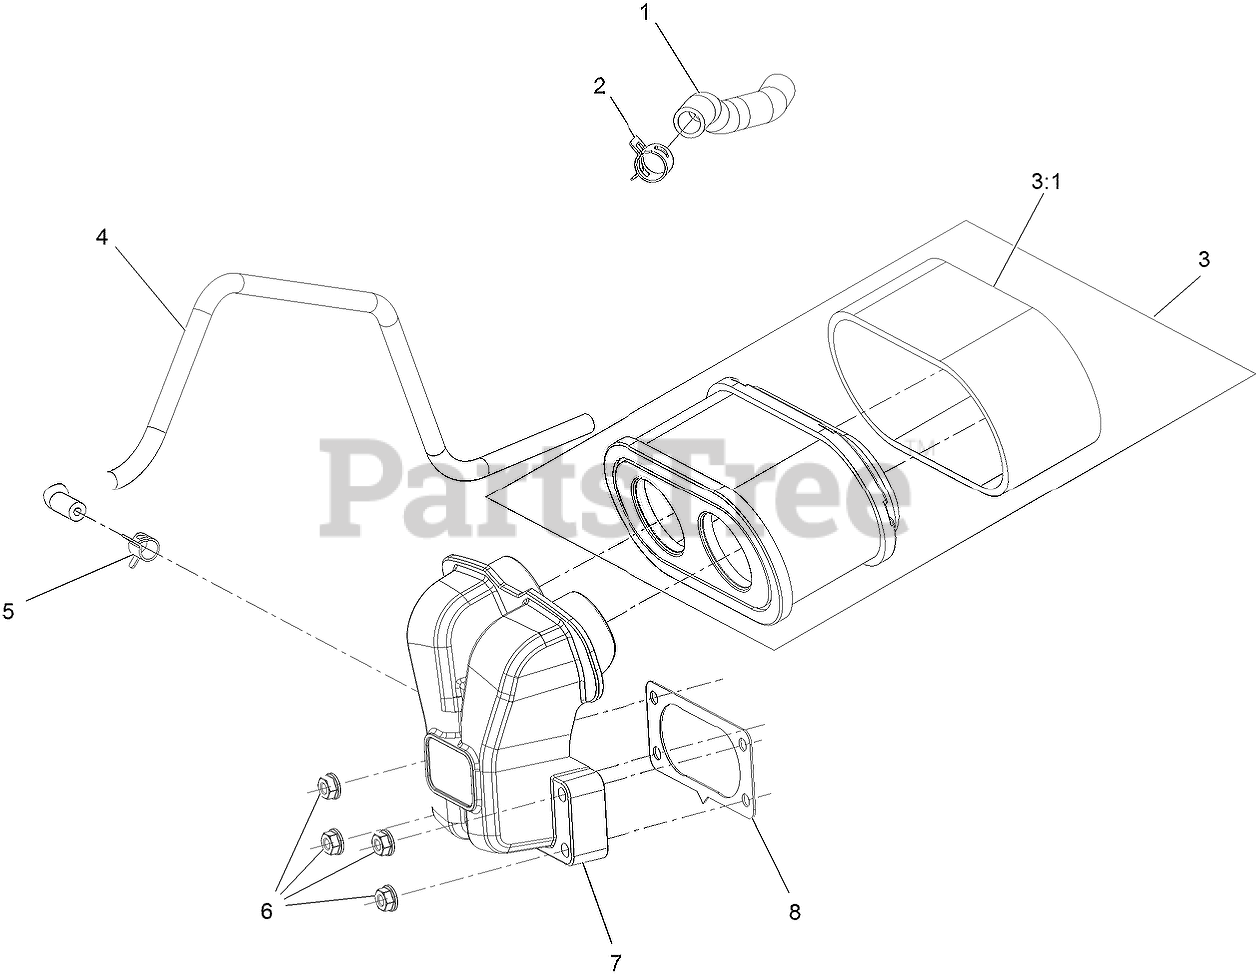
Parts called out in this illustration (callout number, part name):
1	TUBE-BREATHER
2	CLAMP-HOSE
3	AIR FILTER KIT
3:1	PREFILTER
4	HOSE-FUEL
5	CLAMP-HOSE
6	NUT-FLANGE
7	MANIFOLD-FILTER, AIR
8	GASKET-CARBURETOR
